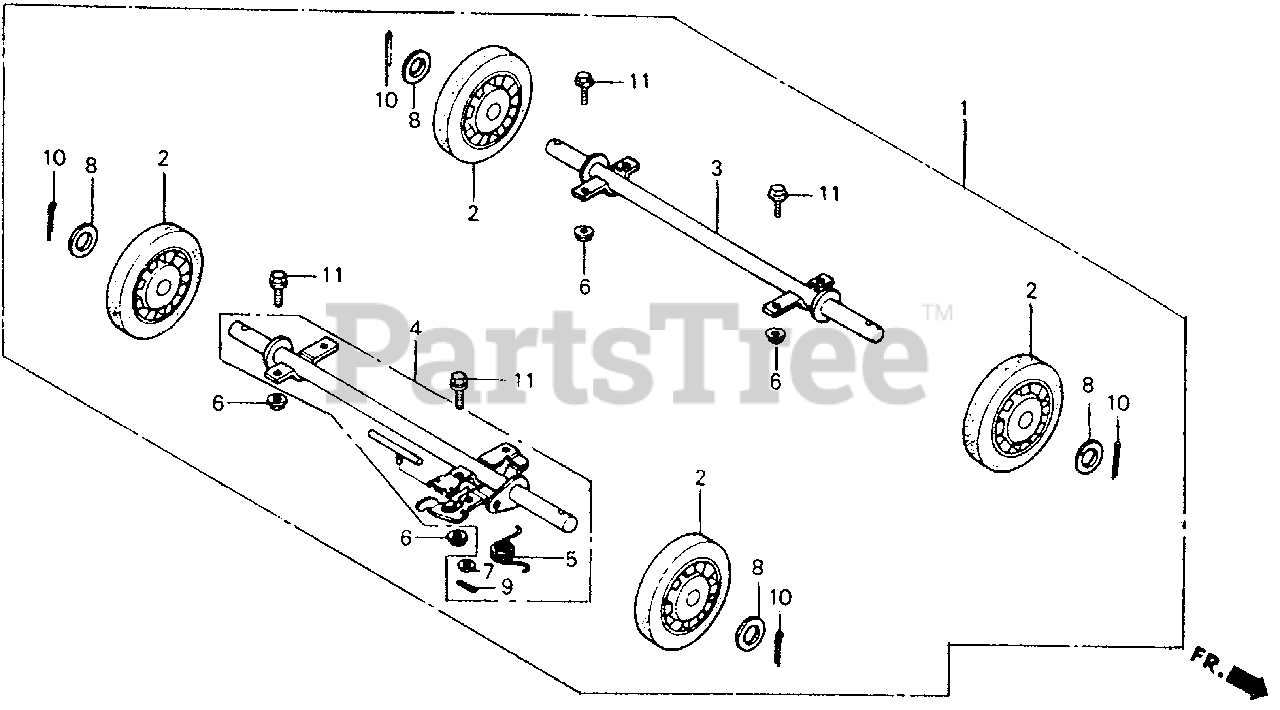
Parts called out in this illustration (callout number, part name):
1	WHEEL KIT (4-WHEELS)
2	WHEEL
3	SHAFT, R. WHEEL
4	SHAFT ASSY., L. WHEEL
5	SPRING, WHEEL STOPPER
6	NUT, FLANGE (8MM)
7	WASHER, PLAIN (6MM)
8	WASHER, FLAT (20MM)
9	PIN, COTTER (2.0X12)
10	PIN, COTTER (4.0X30)
